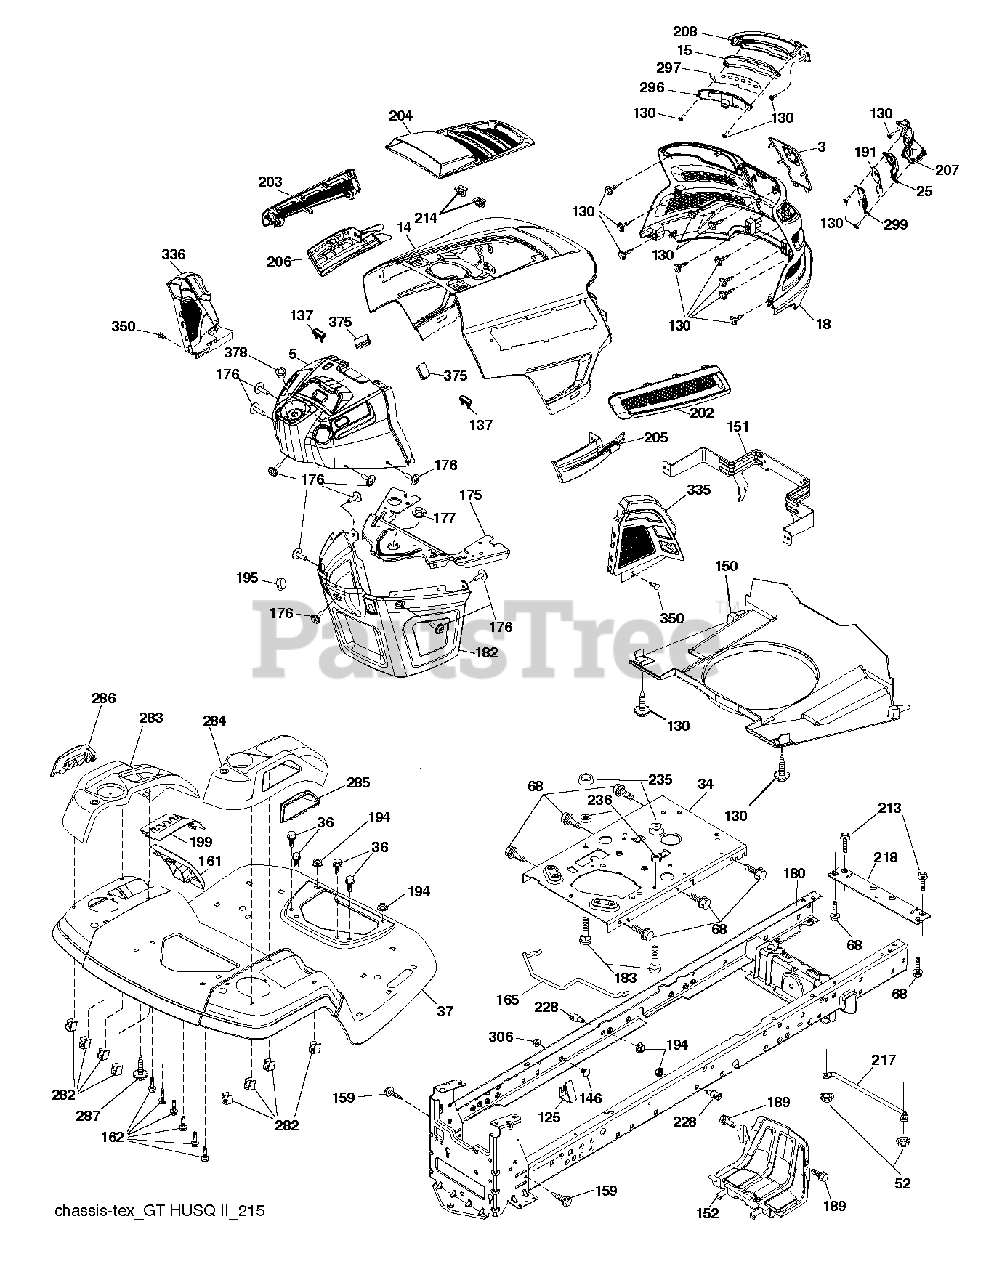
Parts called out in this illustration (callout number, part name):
3	APPLIQUE.SUBASM.GT.HUSQ.II
5	DASHBOARD TEX;GT2;UPPER S_M_
14	HOOD.ASM.HUSQVARNA.GT.TEX.ORAN
15	LED LIGHT.LH
18	GRILLE SUBASM.GT.II.LOW.HDLGHT
25	LENS.RH
34	PLATE.ENGINE.WELDED.CHASSIS
36	SCREW 5/16"
37	FENDER.TLT.FS.W/CPH/FW/RSF.668
52	LOCKNUT
68	SCR 5/16-18 X 1/2 SELFTAP ZN
125	CLIP.FUEL.LINE
130	SCREW.#10 X 0.750.BOS
137	BUMPER DASH
146	BOLT.RDHD.SHT.SQNK.3/8-16X5/8
150	AIR.DUCT.GTV.BLACK
151	BRACKET.PIVOT.HOOD.GT.HUSQ.II
152	SHIELD.BROWNING.PNT.GT.V2
159	SCREW, 3/8-16X3/4
161	WINDOW.FUEL.LT.HUSQ.TEX.498
162	SCREW.HI-LO.CONSOLE
165	SUPPORT.TANK.REAR.W/TEX
175	Crossmember Plate
176	SCREW.#10-24X5/8.RN.QU
177	BUSHING STEERING
180	CHASSIS
182	DASH.LOWER.COMMON.12V.ADAPTOR
183	BOLT.5/16-18X1-1/4 FULL THD
189	SCREW
191	INSERT INFLECT.RH
194	NUT LOCK HEX FLANGE 5/16-18
195	PLUG.HOLE.DASH.LOWER.12V.BLK
199	PLATE.DECK.LIFT.HUSQ.LT
202	VENT.SIDE.RH.GT.HUSQ.II.
203	VENT.SIDE.LH.GT.HUSQ.II.498
204	VENT.TOP.HUSQ.GT2
205	SIDE.TRIM.RH.GT.HUSQ.II
206	SIDE.TRIM.LH.GT.HUSQ.II.GRAY
207	BEZEL GT2 LED RH W/ LOWER.ATT
208	BEZEL GT2 LED LH W/ LOWER ATT
213	BOLT
214	CLIP.RETAINER.TINNER.
217	ROD.PIVOT.HOOD
218	X-PIECE.HOOD.STOP.NON/
228	STUD.FASTNER.W/ANTI-ROTATE
235	SPACER FENDER
236	NUT.CENTERLOCK.5/16-
282	CLIP.RETAINER.CONSOLE.LT.HUSQ
283	CONSOLE.DECK.LIFT.R.SDFL.HUSQ
284	CONCOLE.CNTRL.PDL.HUSQ.LT.498
285	CONSOLE INSERT RH
286	CONSOLE.INSRT.LH.HUSQ.LT.BLACK
287	SCREW 1/4X20
296	LED LIGHT.LH
297	INSERT REFECT LH
299	LED LIGHT.RH
306	NUT LOCK FLG 3/8-16 UNC
335	COVER.LOWER.DASH.RH.BLACK
336	COVER-LH.LOWER.DASH.GT2.BLACK
350	CLIP.X-MAS.TREE
375	BUMPER CLIP-ON. DASH 1"
378	BUSHING FLANGE; PLASTIC
